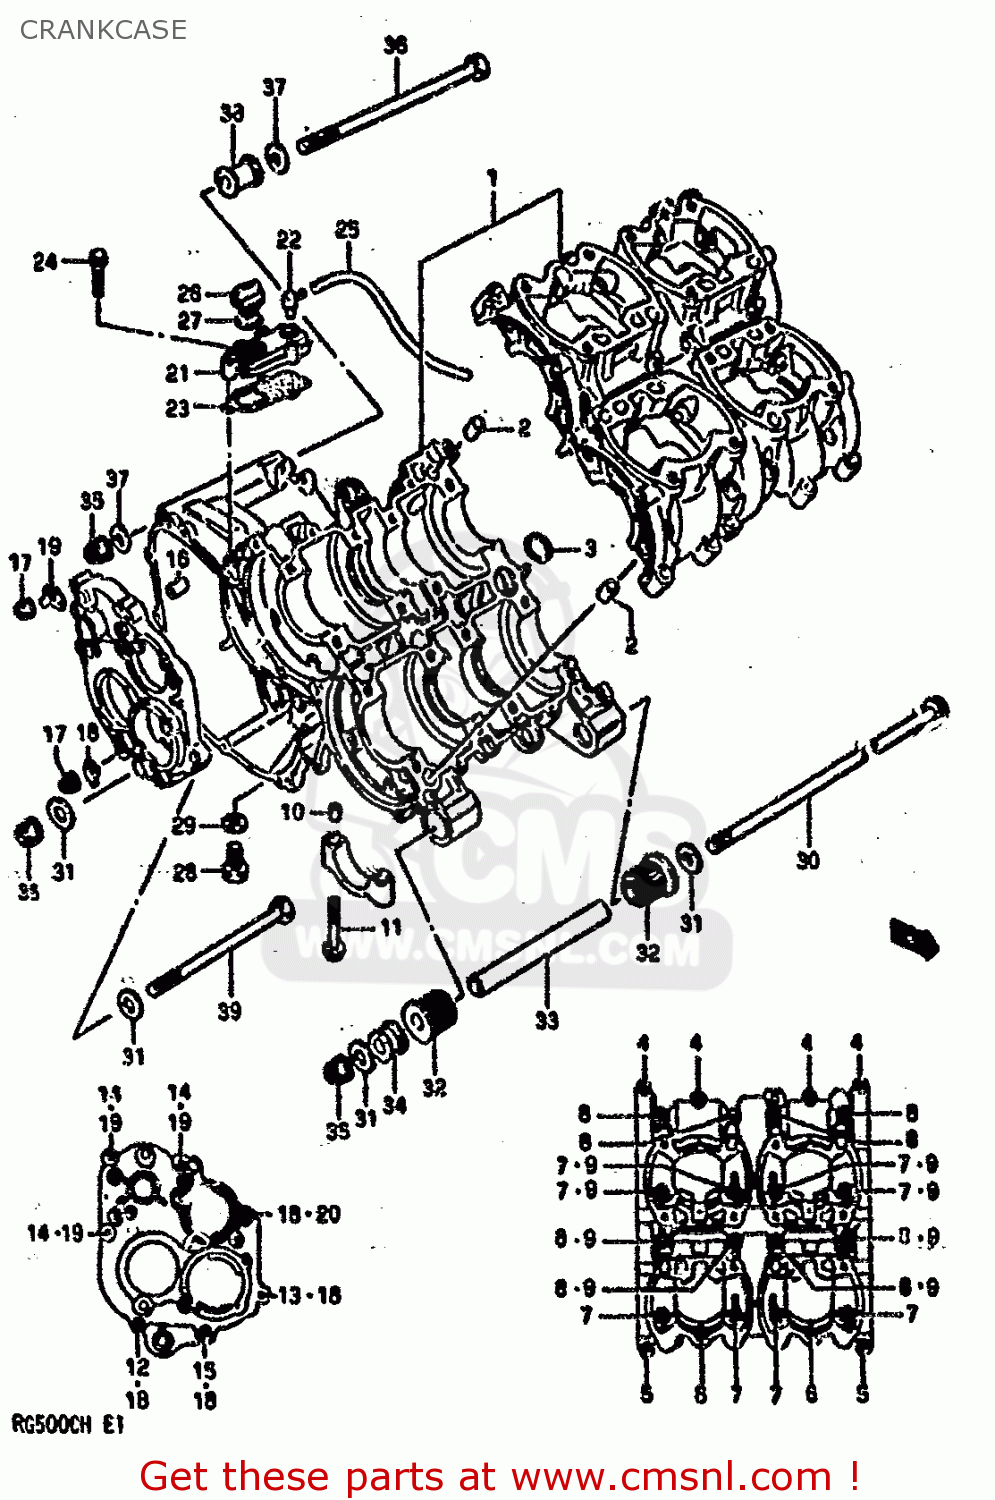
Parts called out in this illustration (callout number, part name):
1	CRANKCASE SET
2	PIN(10.4X13X22)
3	O RING(D:2.3,ID:24.4)
4	BOLT 6X35
5	BOLT (6X45)
6	BOLT
7	BOLT
8	BOLT
9	GASKET(8.2X14X1) (NAS)
10	PIN
11	BOLT
12	STUD BOLT (6X18)
13	STUD 6X25
14	STUD 6X30
15	STUD BOLT (6X37)
16	PIN(8.4X11X18)
17	NUT 6MM
18	RETAINER,T/M COVER NO.1
19	RETAINER,T/M COVER NO.2
20	BOLT
21	CAP SET,BREATHER
22	UNION,BREATHER HOSE
23	GASKET,BREATHE
24	BOLT
25	HOSE
26	PLUG,OIL FILLE
27	O RING(D:3.1,ID:16.8)
28	BOLT
29	GASKET(12.1X16.2X3.7) (NAS)
30	BOLT (10X330)
31	WASHER (10.5X24X2.3)
32	BUSH
33	SPACER (L:142)
34	SPACER,ENGINE MOUNT(L20)
35	NUT 10MM
36	BOLT
37	WASHER
38	SPACER,ENGINE MOUNT
39	BOLT 10X170
